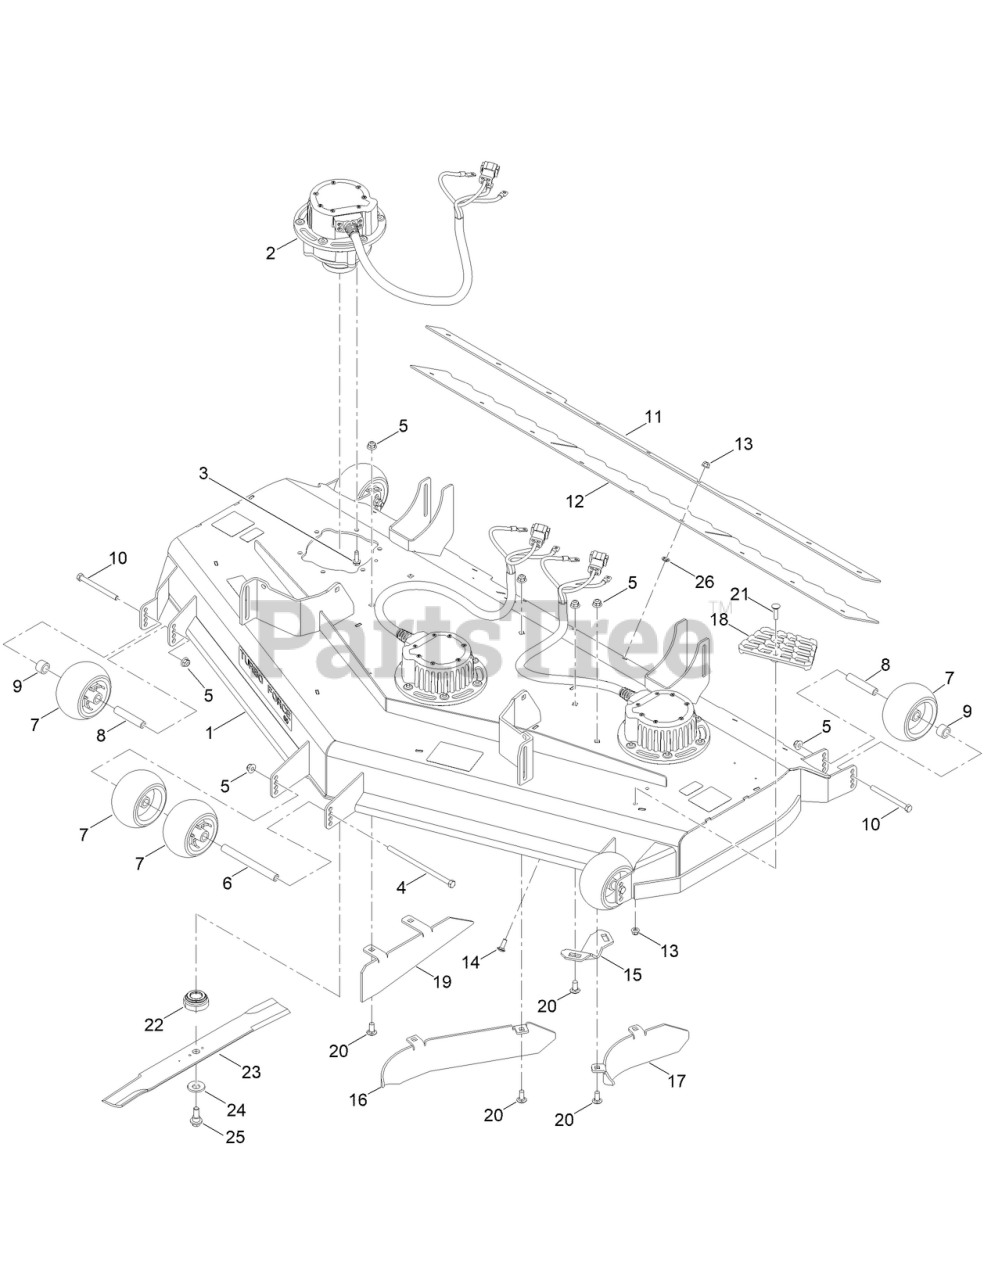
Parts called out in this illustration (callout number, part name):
1	DECK ASM-60IN, RD
2	MOTOR/GEN-48V,
3	SCREW-THD ROLL, HWH
4	SCREW-HH
5	NUT-HF, NI
6	SPACER-WHEEL
7	ROLLER-SCALP, ANTI
8	TUBE-SHAFTING
9	TUBE-SPACER
10	SCREW-HH
11	BRACKET-CLAMP
12	DEFLECTOR-RUBBER
13	NUT-HF, NI
14	BOLT-CARR
16	BAFFLE-INNER, CENTER
17	BAFFLE-INNER, LH
18	STEP-DECK
19	BAFFLE, LONG RH
20	SCREW-CARR
21	SCREW-CARR
22	RETAINER-BLADE
23	BLADE-20.5IN, MED SAIL
24	WASHER-BELLEVILLE
25	SCREW-SHOULDER,HWH
26	NUT-PUSH
